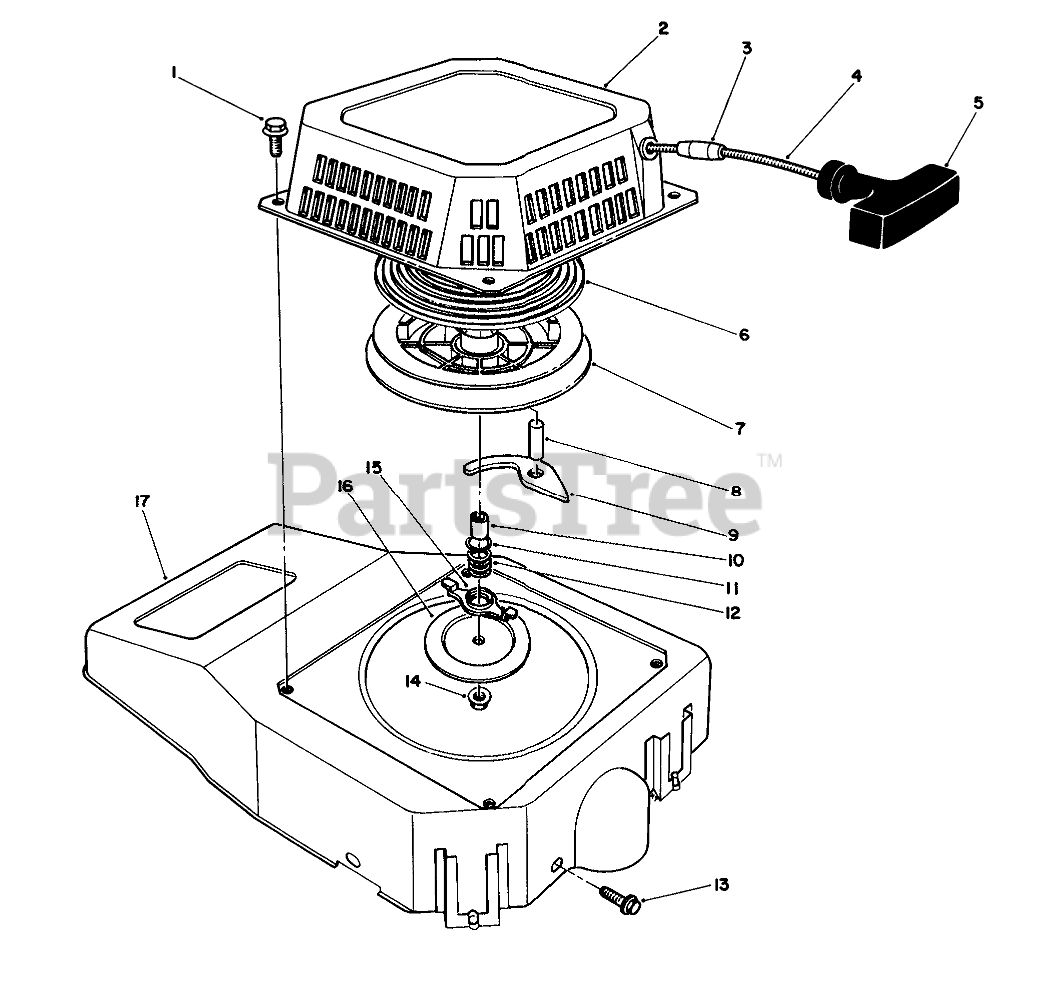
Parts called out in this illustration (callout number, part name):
1	SCREW-HHF
2	Case-Recoil
4	ROPE-STARTER
5	HANDLE
6	SPRING
10	Spacer
11	WASHER
12	Spring-Friction
15	Guide-Paw
16	PLATE
17	SHROUD
